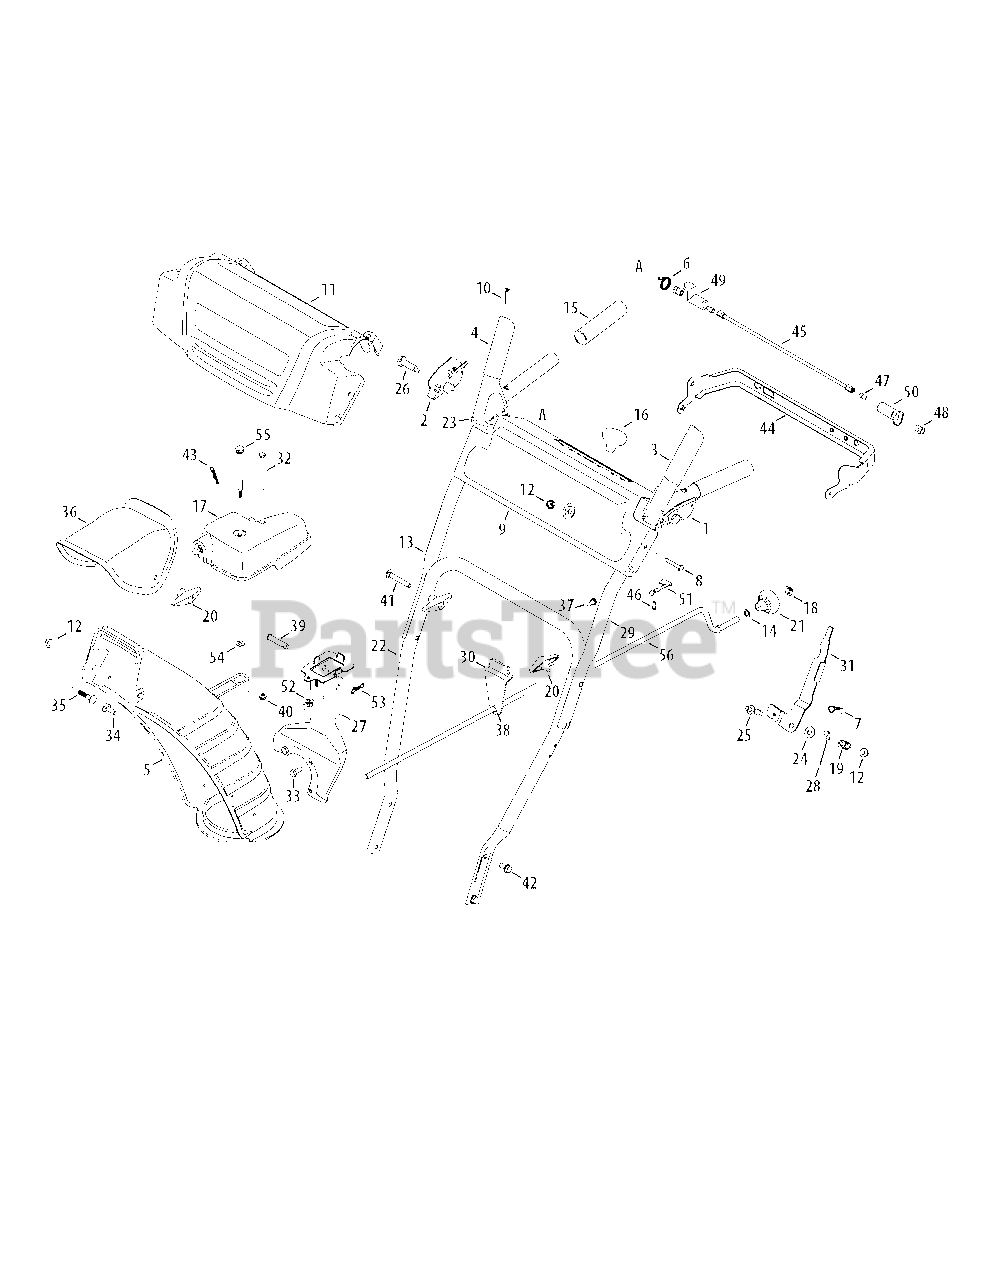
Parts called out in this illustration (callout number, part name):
1	Handle Assembly, Clutch Lock, LH
2	Handle Assembly, Clutch Lock, RH
3	Handle Ass’y, Engage, LH
4	Handle Ass’y, Engage, RH
5	Chute, Lower
6	Spring, Torsion, .8156 ID x .3038
7	Click Pin
8	Screw, 1/4-20 x 1.625
9	Panel, Handle, (no cutout)
10	Screw, Machine, #10-24, 1.375
11	Handle Panel Cover
12	Nut, Flange Lock, 5/16-18, Nylon
13	Handle, Upper, RH
14	Washer, Flat, .375 x .738 x .063
15	Grip, 1.0 ID x 5.0
16	Knob, Shift, Black
17	Gearbox Assembly
18	Cap, Push, 3/8 Rod
19	Spring, .39 x .60 x .88
20	Knob, 5/16-18, Black
21	Crank Knob
22	Handle, Lower
23	Bumper, Rubber, .62 OD x .22
24	Washer, Flat, .385 x .870 x .092
25	Bolt, Shoulder, 5/16-18 x 0.905
26	Screw, Shoulder, .43 x 1.3, 1/4-20
27	Bracket, Chute Support
28	Cable, Speed Selector
29	Handle, Upper, LH
30	Bracket, Rod
31	Shift Lever
32	Screw, 1/4-20 x 3.00
33	Screw, 5/16-24 x .750
34	Bolt, Carriage, 5/16-18, 1.0
35	Bolt, Carriage, 5/16-18, .750
36	Chute, Upper, w/ Label
37	Screw, 1/4-20 x .625
38	Bushing, Plastic, .380
39	Pin, Clevis
40	Nut, Flange Lock, 1/4-20
41	Screw, Carriage, 5/16-18, 2.25
42	Screw, 5/16-18, 2.25, Gr5
43	Pin, Cotter
44	Bracket, Panel
45	Rod, Pivot
46	Screw, #8-16 x .50
47	Screw, 1/4-20 x .50
48	Nut, Hex, 1/4-20
49	Plate, Lock
50	Cam, Clutch Lock
51	Spring, Clutch Lock
52	Nut, Wing
53	Bow-Tie Cotter Pin
54	Washer, Flat, .25 x .630 x .0515
55	Scr. Shldr. Flg., .312 x 3.5 x 1/4-20
56	Crank, Chute
